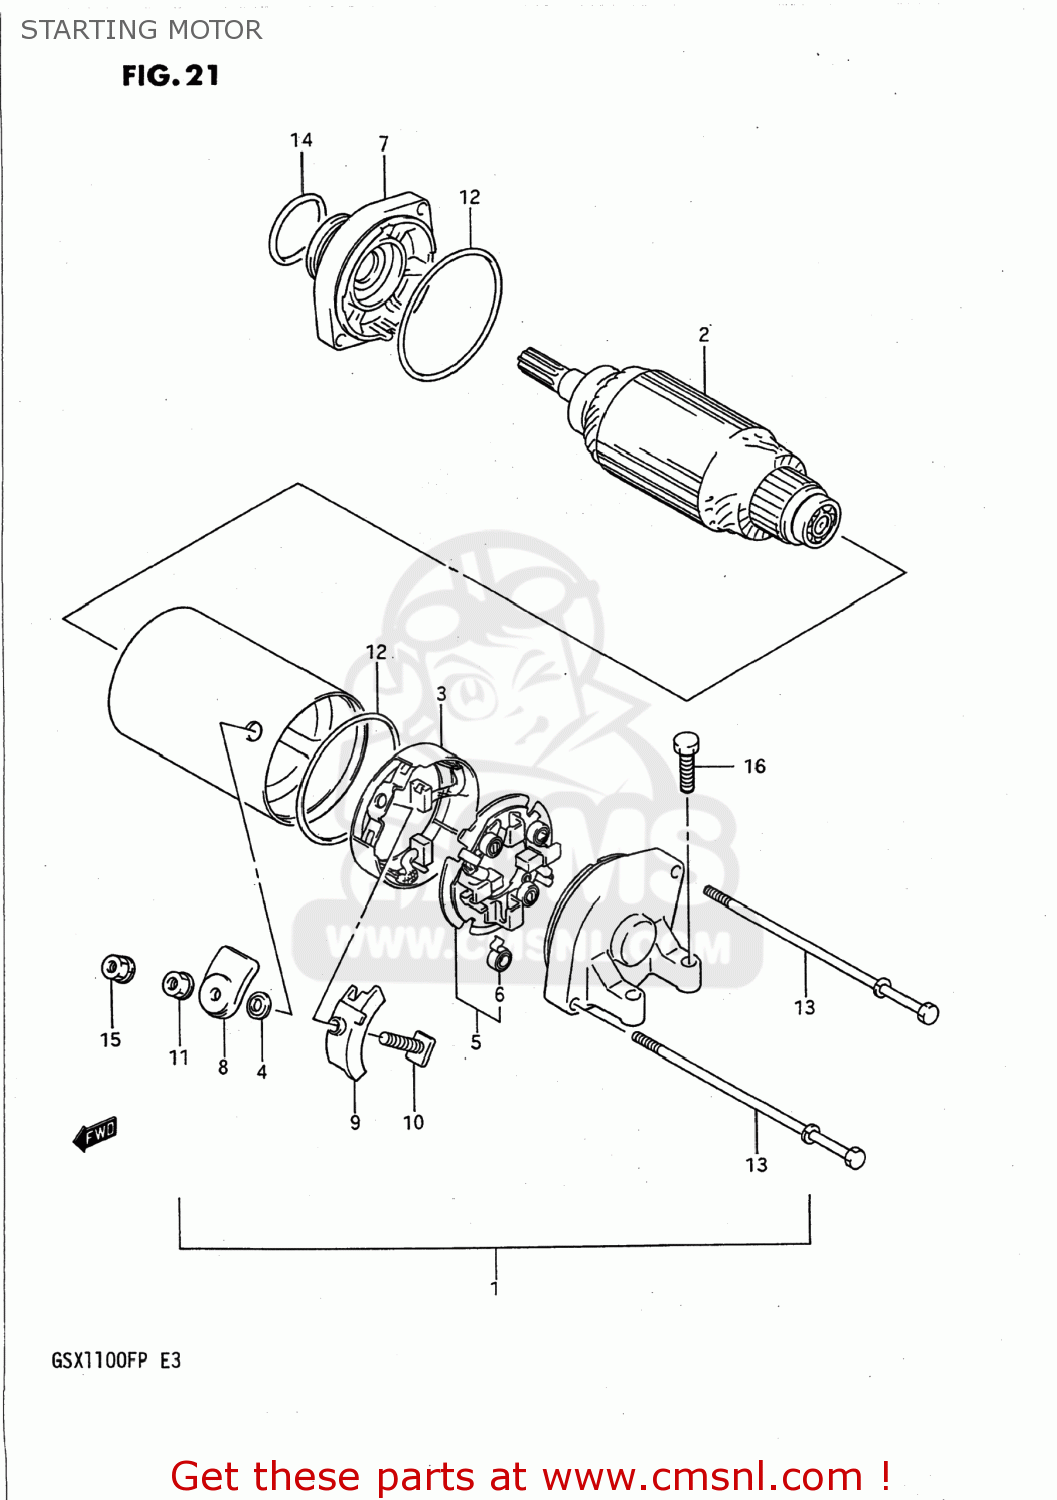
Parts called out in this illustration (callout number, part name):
1	MOTOR ASSEMBLY,STARTING
2	ARMATURE
3	TERMINAL SET,BRUSH
4	GASKET (NAS)
5	HOLDER SET,BRUSH(-)
6	SPRING
7	BRACKET SET
8	BUSHING
9	BUSHING
10	BOLT
11	NUT
12	O RING
13	BOLT,STARTING
14	O RING
15	NUT
16	SCREW (6X25)
